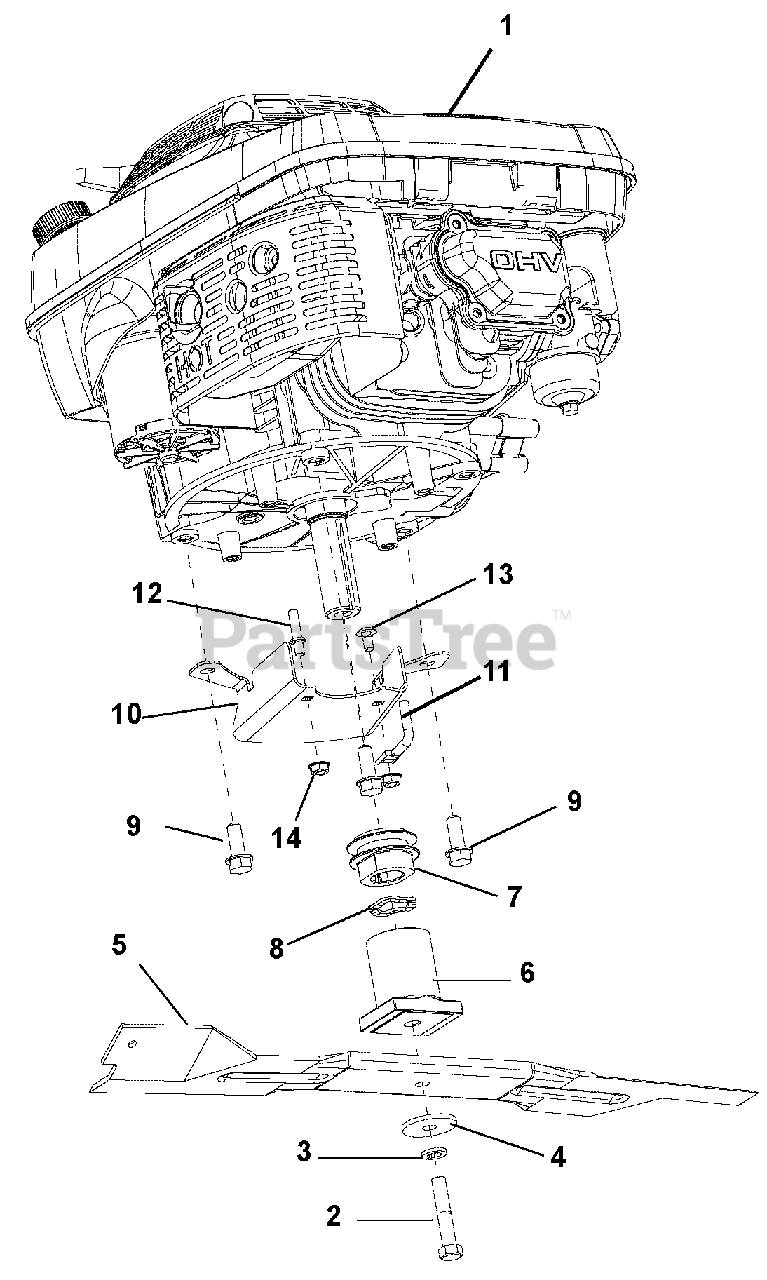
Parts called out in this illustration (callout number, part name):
1	Engine, KAWI FJ180V Commercial
2	Bolt, Hex .38-24 x 2.00 Grade 8
3	Washer, Locking .38 x .094 Regular
4	Washer, Flat-Steel .39 x 1.5 x .125
5	21" Mower Blade
6	Adapter, CE Blade
7	Pulley-Sintered Iron LM
8	Washer, Wave .885 x 1.311 x .125
9	Screw, Tapping .38-16 x 1.00 Hex Washer Head Thread
10	Channel, XD21 Front Belt
11	Finger, Belt
12	Finger, Belt
13	Bolt, Round Head Square Neck .25-20 x .50 Grade 5
14	Nut, Locking-Flange .250-20
